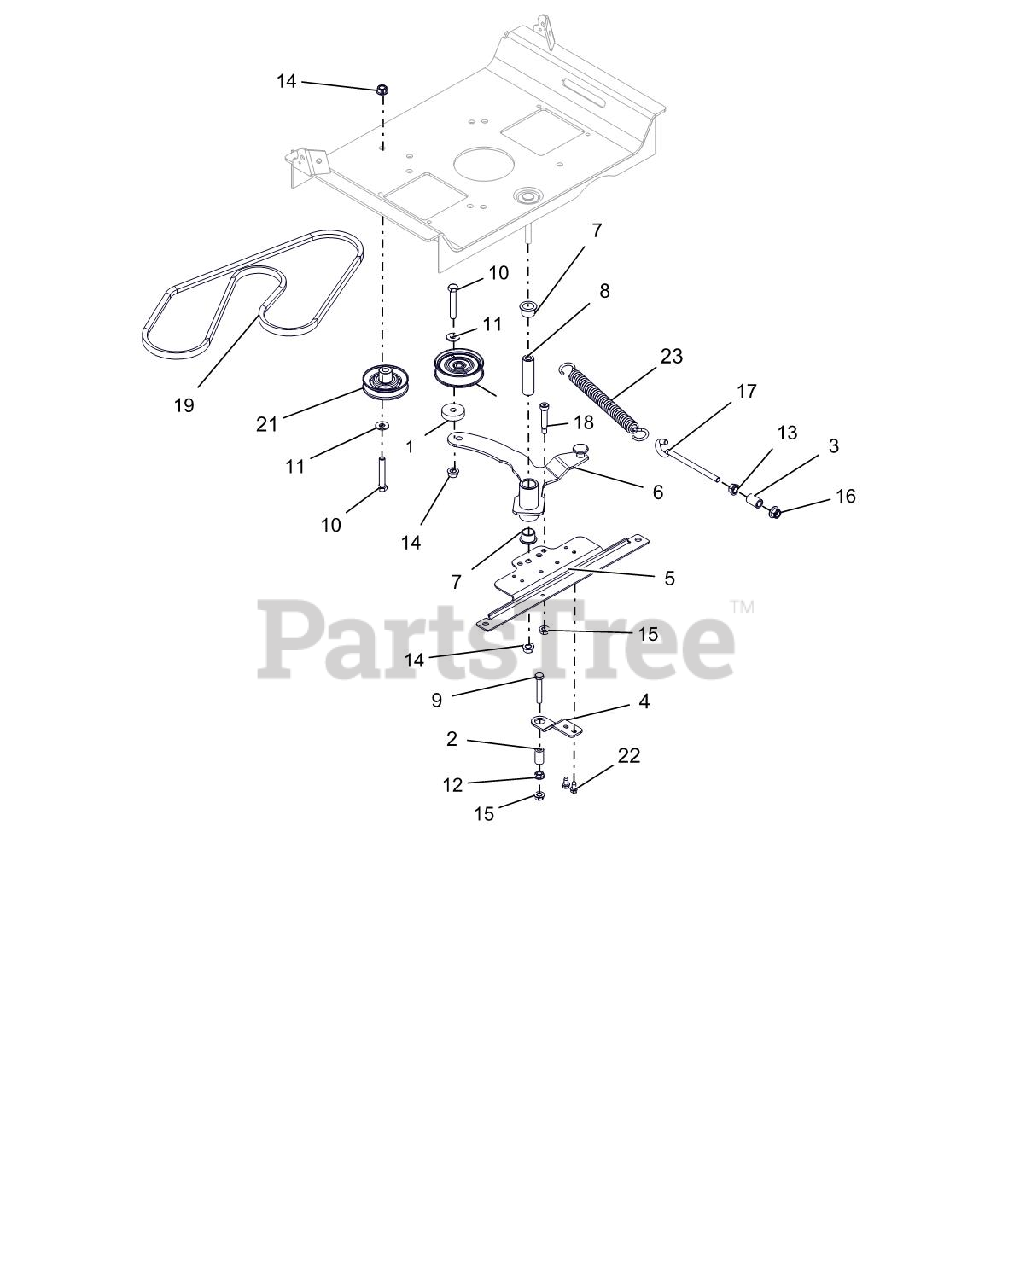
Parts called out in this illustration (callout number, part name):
1	SPACER, .39 X 1.50 X .380
2	SPACER, RUBBER 5/16 IDX1.0 LG
3	SPACER, .375X.625X.970 (PM)
4	BRKT, CLUTCH STOP
5	BRKT, DRIVE IDLER MOUNTING
6	WLDMT,GRD DRIVE IDLER ARM-LGR
7	BSHG-FLG 0.75X0.875X.625X1.125
8	BUSHING, SLEEVE .38X.750X2.78
9	@BLT-HEX .31-18X2.00 GR5 YWZC
10	@BLT-HEX .38-16X2.25 GR5 YWZC
11	WSHR-FL-STL.38X.875X.083 YWZC
12	NUT-SPNLK-FLG .312-18 YWZC
13	NUT-SPNLK-FLG .375-16 YWZC
14	@NUT-LK-TOP-FLG .38-16 YWZC
15	NUT-LK-TOP-FLG .31-18 YWZC
16	@NUT-LK-NYL-FLG .38-16 YWZC
17	BOLT,.38-16 X 4.25-.62 DIA EYE
18	BLT-SHLDR .38X1.5X.31-18 SLT Y
19	V-BELT, A-RAW EDGE
20	IDLER, FLAT - 3.05" X .75"
21	ASM, 3.00" V IDLER
22	SCR-TAP .25-20X.50 HWH TR YWZ
23	SPRING, EXTENSION
